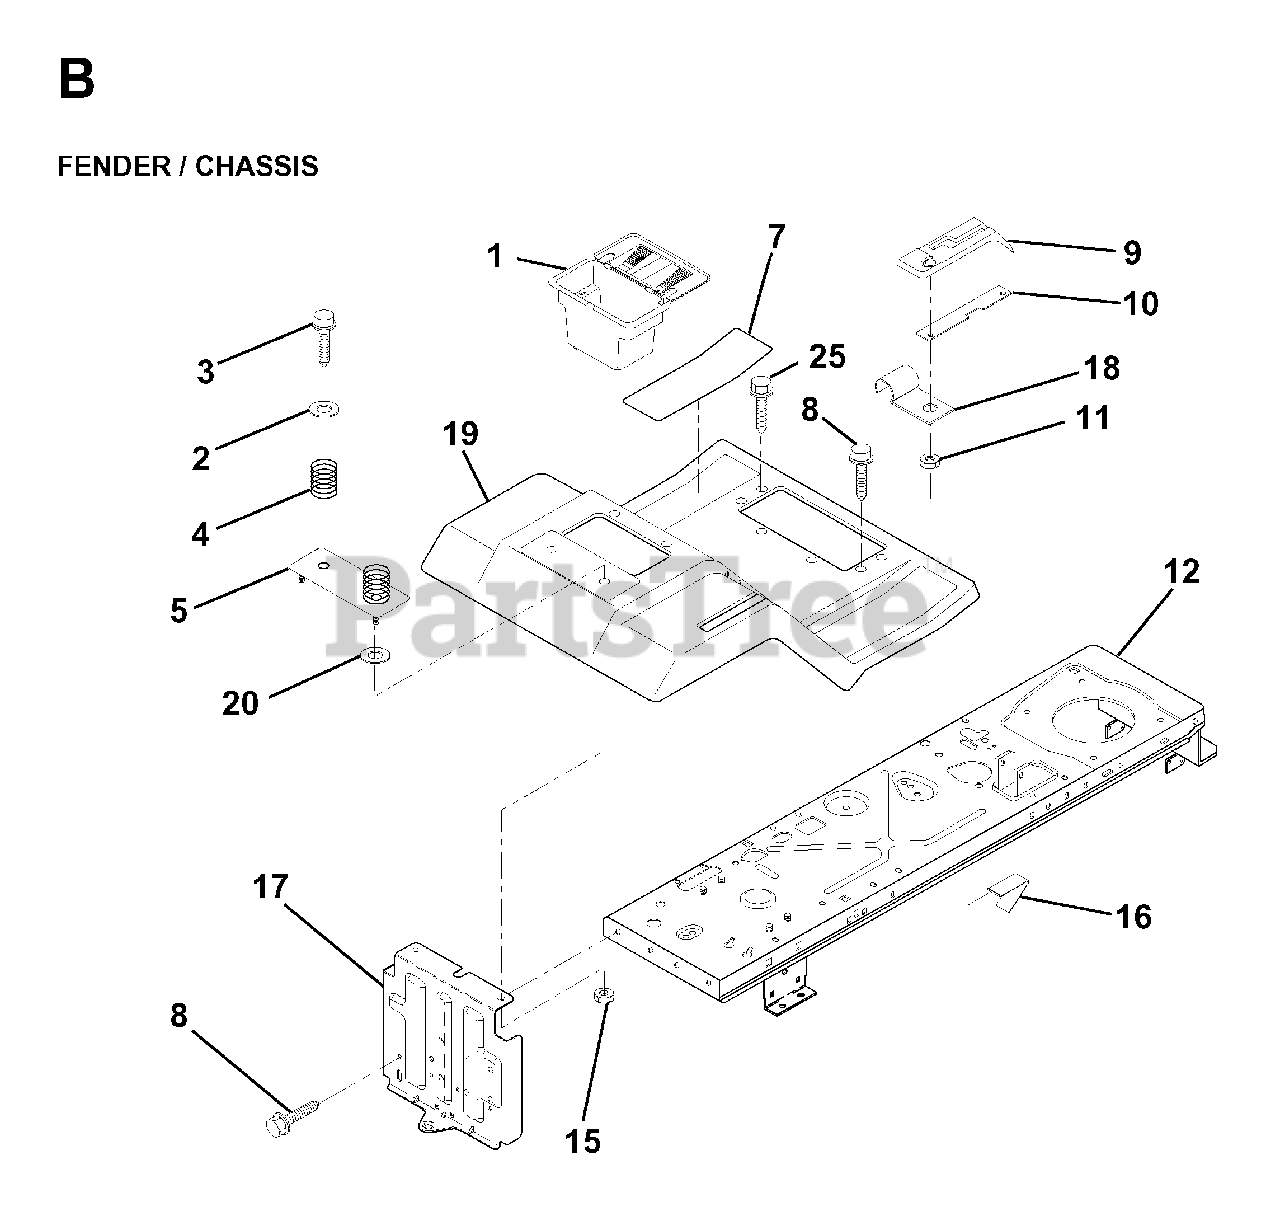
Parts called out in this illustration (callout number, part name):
1	CASE BATTERY MECH HINGE
3	SCREW
4	SPRING COMPRESSION
7	PAD FOOTREST
8	SCREW
9	CONSOLE SHT CONTR
10	BAR, SHIFT LOCK
18	CLIP,INSULATOR
20	WASHER
